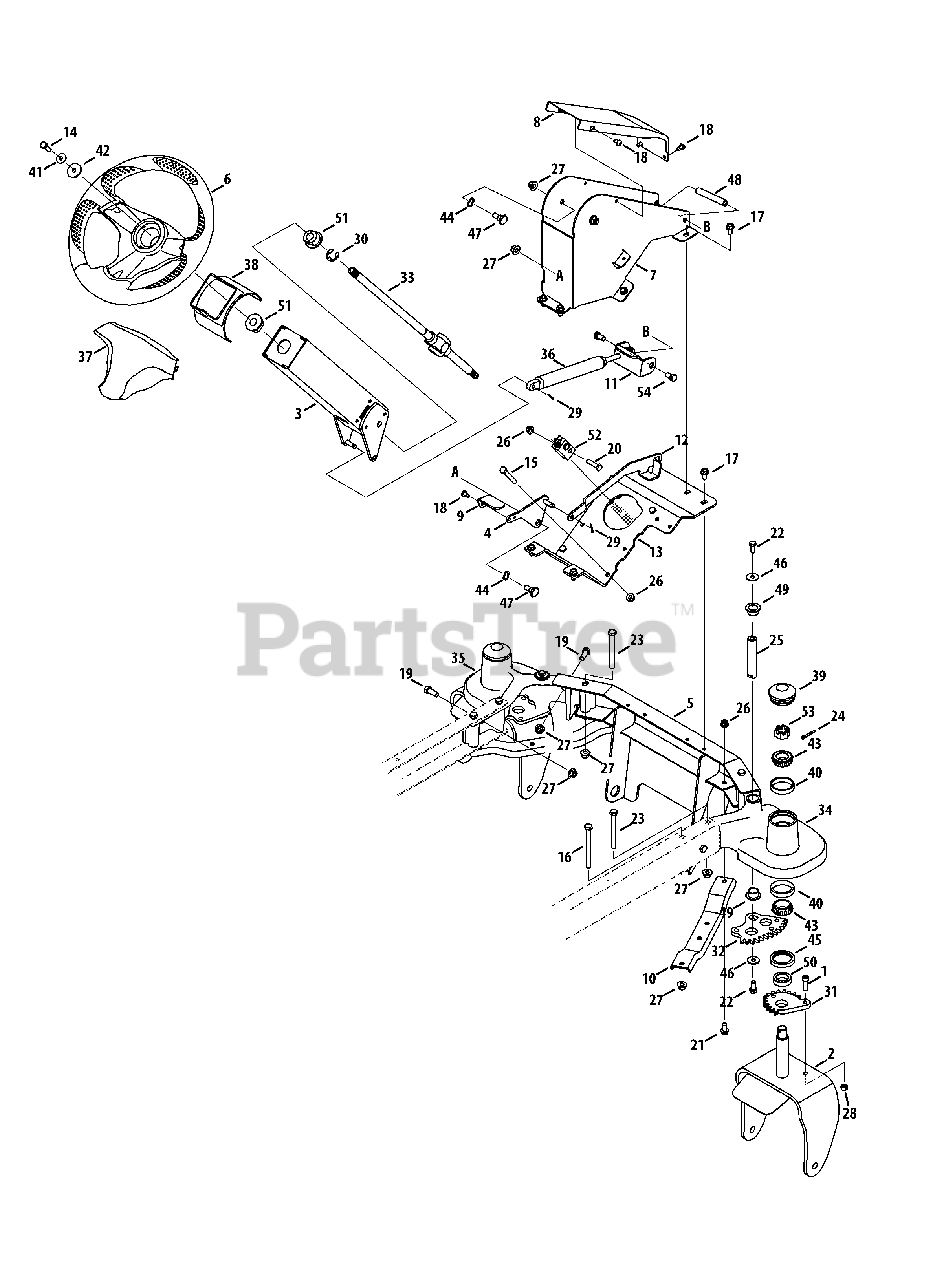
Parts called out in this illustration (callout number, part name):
1	Socket Head Screw, 5/16-18 x 1.00
2	Caster Bracket Assembly
3	Upper Steering Column Assembly
4	Tilt Release Pedal Assembly
5	Front Bumper Frame Assembly
6	Steering Wheel Assembly
7	Lower Steering Wheel Column
8	Lower Column Cover
9	Tilt Steering Pedal
10	Front Frame Brace
11	Damper Pivot Lower Bracket
12	Tilt Action Lever
13	Steering Mount Box Plate
14	Hex Screw, 5/16-18 x 1.00
15	Hex Screw, 5/16-18 x 2.25
16	Hex Screw, 3/8-16 x 4.00
17	Hex Washer Screw, 5/16-18 x .750
18	Screw, 1/4-20 x .5
19	Hex Screw, 3/8-16 x 1.00
20	Hex Screw, 5/16-18 x 1.25
21	Hex Washer Screw, 5/16-18 x 750
22	Hex Screw, 5/16-18 x .75
23	Hex Screw, 3/8-16 x 3.50
24	Cotter Pin
25	Pivot Gear Steering Shaft
26	Flange Lock Nut, 5/16-18
27	Flange Lock Nut, 3/8-16
28	Hex Lock Nut, 5/16-18
29	Cotter Pin, 3/32 x .750
30	E-Ring, .750
31	13-Tooth Variable Spur Gear
32	12-Tooth Variable Gear
33	Steering Shaft
34	RH Tpr. Bearing Caster Pivot Axle
35	LH Tpr. Bearing Caster Pivot Axle
36	Locking Damper Cylinder, 80MM
37	Steering Wheel Cover
38	Column Cover
40	Bearing Cup
41	Bell Washer, .340 x .872 x .060
42	Flat Washer, .330 x 1.25 x .120
43	Cone Bearing
44	Wave Washer, .510 x.750 x .017
46	Flat Washer, .344 x 1.00 x .063
47	Shoulder Bolt, 3/8-16 x .496 x .336
48	Tube, .31 ID x .50 OD x 3.56
49	Flange Bearing, 3/4 x .52
50	Spacer, 1.00 ID x 1.50 OD x .437
51	Flange Bearing, .630 x 1.50
52	Steering Shaft Block
53	Slotted Nut
54	Hex Screw, 3/8-16 x .750
